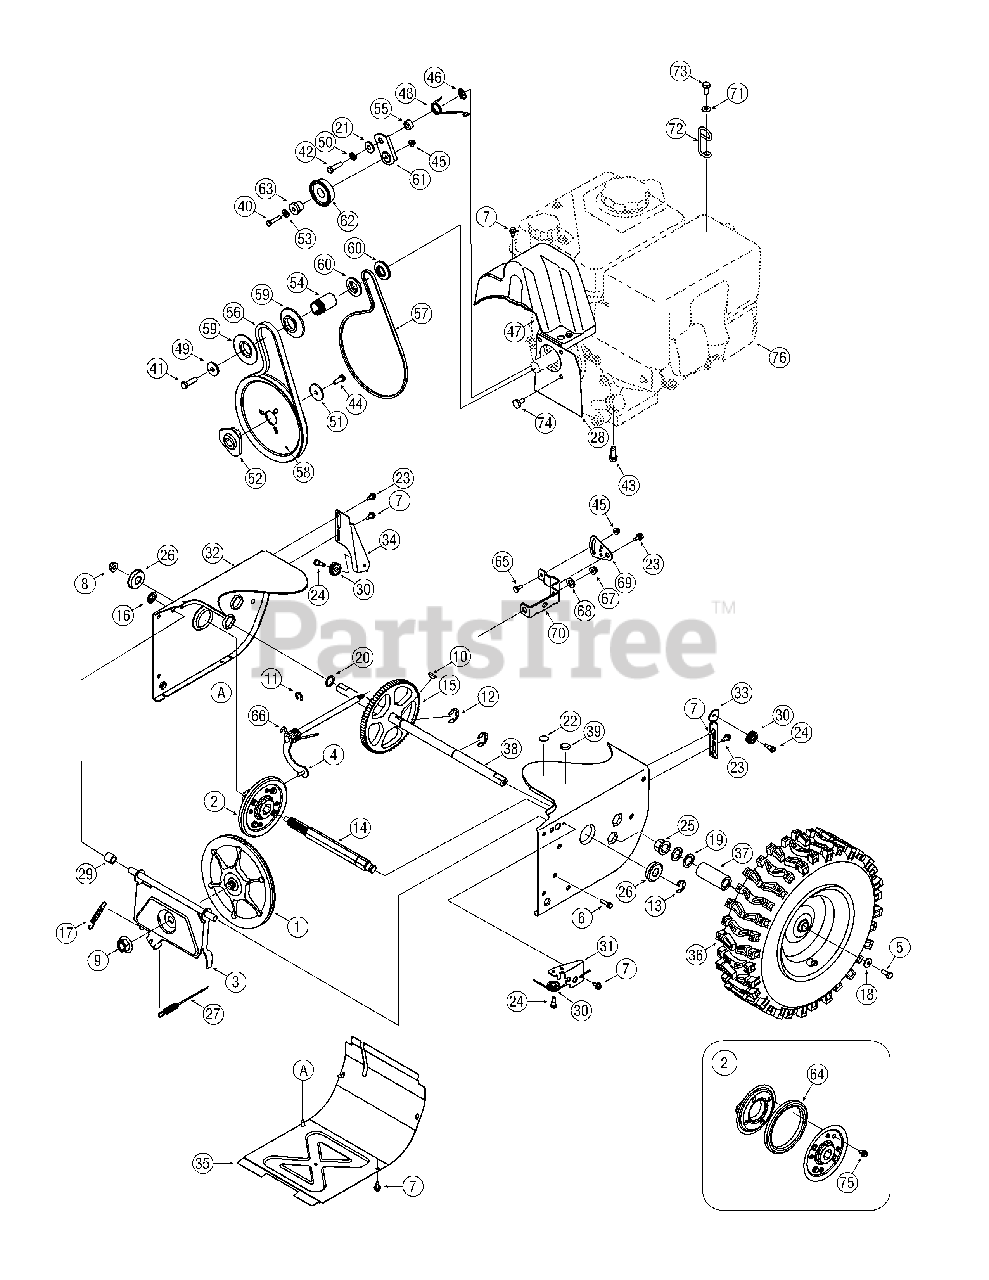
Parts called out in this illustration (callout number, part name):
1	Disc Assembly, Friction Wheel
2	Friction Wheel Assembly, 5.5 OD
3	Support Bracket, Friction Wheel
4	Shift Assembly, Rod
5	Hex Screw, 5/16-24, .750, Gr5
6	Screw, 1/4-20, 1.000
7	Screw, 1/4-20 x .625
8	Nut, Flange Lock, 3/8-16, Nylon
9	Nut, Jam Lock, 5/8-18, Gr5, Nylon
10	Key, Hi Pro, 3/16 x 3/4 Dia.
11	E-ring, .500 Dia.
12	E-ring, Retaining, .875 Dia.
13	E-ring, .750 Dia.
14	Hex Shaft, .8125, 7-Tooth
15	Gear, 80-Tooth
16	Speed Nut, .500
17	Extension Spring
18	Washer, Bell, .340 x .872 x .060
19	Washer, Flat, .793 x 1.24 x .060
20	Washer, Flat, .75 x 1.00 x .060
21	Spacer, Shldr., .3175 ID x .500 x .094
22	Plug, 1/2 ID
23	Screw, Shoulder, .37 x .105, 1/4-20
24	Screw, 1/4-28, .375
25	Bearing, Hex Flange x .75 ID
26	Bearing, Ball, 17 x 40 x 12
27	Clutch Cable, Wheel, 44.95"
28	Plate, Cover
29	Spacer, .508 ID x .75 OD x .68
30	Roller, Cable
31	Front Guide Bracket, Auger Cable
32	Frame
33	Guide Bracket, Auger Cable
34	Guide Bracket, Drive Cable
35	Cover, Frame
36	Wheel Assembly - RH
36	Wheel Assembly - LH
37	Spacer, 1.25 x .75 x 3.0
38	Axle, .75 x 22"
39	Plug, 3/8 ID
40	Hex Screw, 1/4-20, 1.25, Gr5
41	Hex Screw, 3/8-24, 1.25, Gr8
42	Hex Screw, 5/16-24, 1.25, Gr5
43	Screw, Sems, 3/8-16, 1.00
44	Hex Screw, 5/16-24, .875, Gr8
45	Nut, Flange Lock, 1/4-20, Nylon
46	Nut, Push-on, .25 Dia.
47	Cover, Belt
48	Spring, Torsion, .850 ID x .354
49	Washer, Flat, .406 x 1.25 x .157
50	Washer, Lock .3125
51	Washer, Flat, .34 x 1.50 x .150
52	Pulley, Adapter, .75 Dia.
53	Lock Washer
54	Spacer, .875 ID x 1.185 OD
55	Spacer, .340 x .750 x .360
56	Belt, Auger Drive
57	Belt, Wheel Drive
58	Pulley, Auger Drive, 8.1 x .5
59	Pulley, Half, V x 2.600 OD
60	Pulley, Half, 3/8-V x 1.7160 OD
61	Idler Bracket, Wheel Drive
62	Idler Pulley Assembly
63	Spacer, Shoulder, .26 x .79 x .538
64	Rubber, Friction Wheel, 5.5 OD
65	Hex Screw, 1/4-20, .620, Gr5
66	Spring, Torsion, .750 ID x .968
67	Nut, Flange Lock, 5/16-18, Nylon
68	Washer, Flat, .469 x .875 x .105
69	Pivot Bracket, Speed Selector
70	Shift Bracket, Speed Selector
71	Washer, Flat, .330 x .630 x .0635
72	Cable Control Wire
73	Screw, M8-1.25
74	Shoulder Screw
75	Screw, AB, 1/4-20 x .500
76	Replacement Engine
